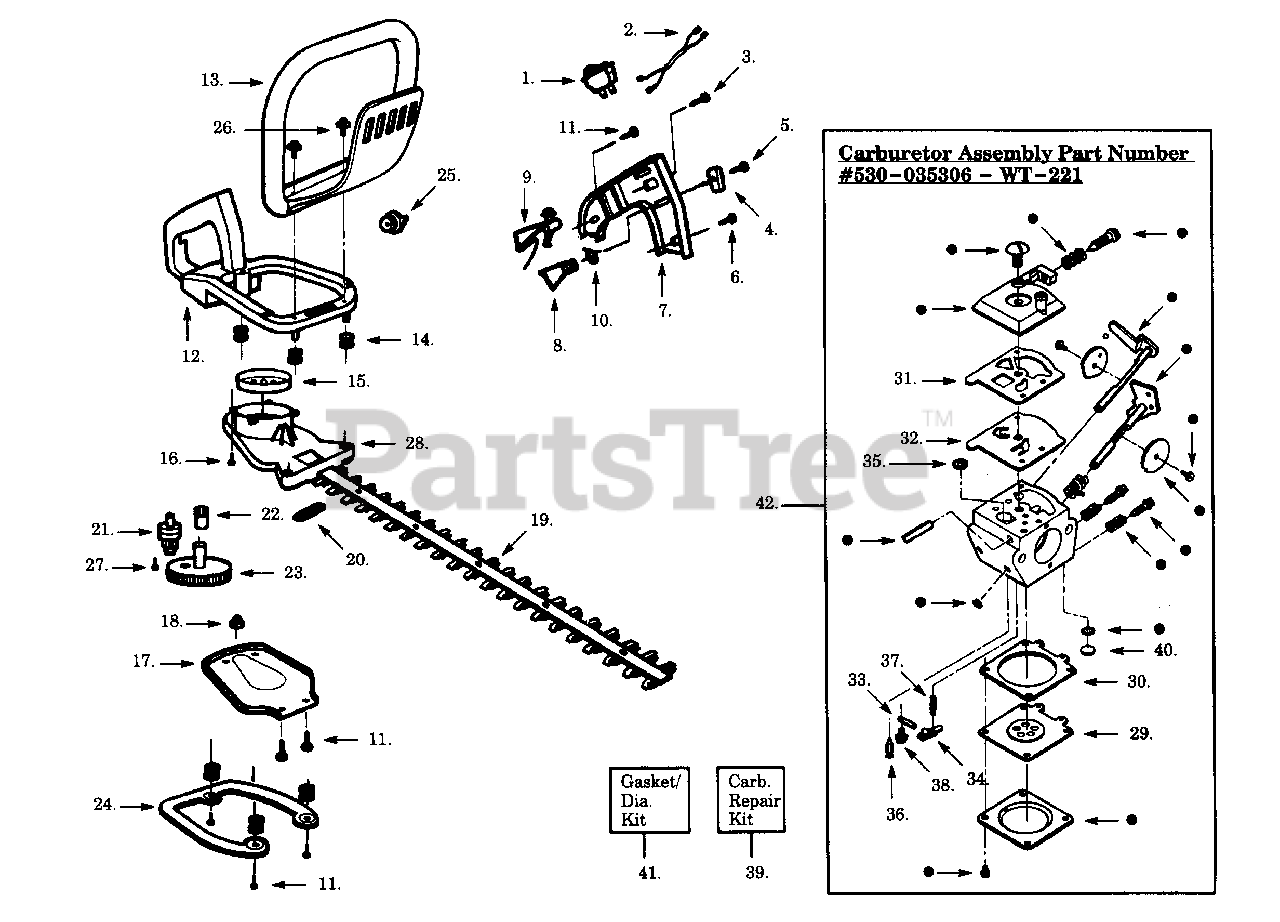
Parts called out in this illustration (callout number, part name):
1	Ignition Switch
2	Lead Wire Ass'y.
4	Trigger Lever
7	Handle Cover
8	Throttle Trigger
9	Throttle Lockout
10	Trigger Spring
12	Rear Handle & Tank Ass'y.
13	Front Handle
14	Isolator Spring
15	Clutch Drum
17	Gear Box Plate
18	Bushing Blade
19	Blade Ass'y. (19")
20	Blade Seal
21	Pinion Ass'y.
22	Drive Gear Bearings
23	Drive Gear Ass'y.
24	Isolator Plate
25	Fuel Cap Ass'y.
27	Screw
28	Gear Box Ass'y.
29	Metering Diaphragm
30	Metering Diaphragm Gasket
31	Pump Gasket
32	Pump Diaphragm
33	Metering Pin
34	Metering Lever
35	Fuel Inlet Screen
36	Inlet Needle Valve
37	Metering Lever Spring
38	Metering Lever Pin Screw
39	Carburetor Repair Kit
40	Welch Plug
41	Gasket/Diaphragm Kit
42	Carburetor Ass'y.
